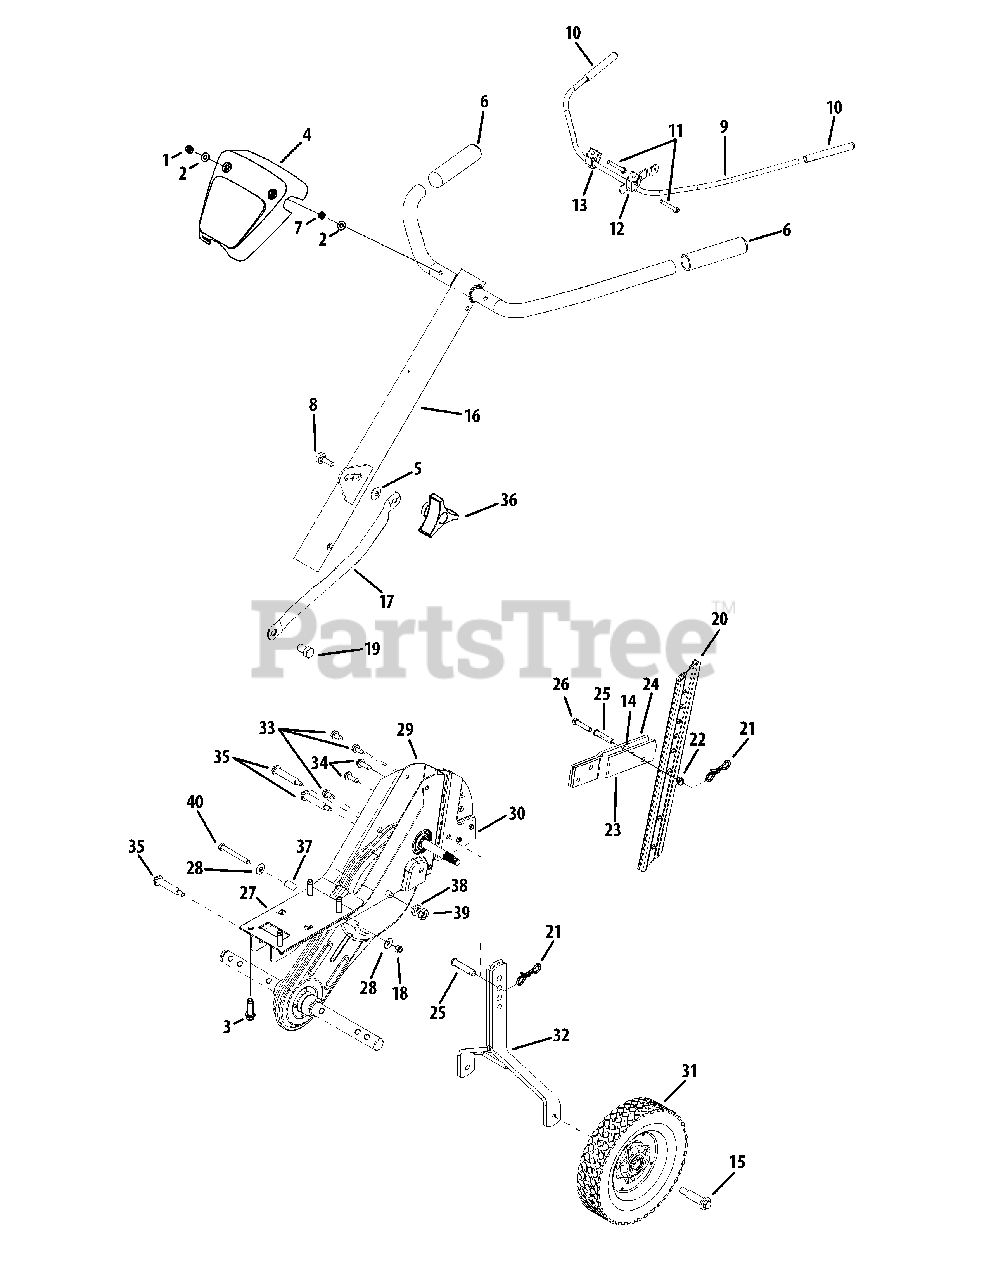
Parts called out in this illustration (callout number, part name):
1	Acorn Lock Nut, 1/4-20
2	Flat Washer, 271" x630"
3	Screw, 3/8-16 x 1250
4	Handle Cover
5	Bell Washer, 34"
6	Handle Grip
7	Jam Nut, 1/4-20
8	Carriage Bolt, 5/16-18 x 1
9	Clutch Handle Assembly
10	Clutch Grip
11	Hex Bolt, 1/4-20 x 225"
12	Clutch Handle Holder
13	Flat Washer, 385" x 62"
15	Shoulder Screw, 496 x 1445
16	Handle Assembly Complete
17	Handle Brace
18	Nylon Hex Nut, 5/16-18
19	Hex Bolt, 1/2-20
21	Cotter Pin, Bow Tie
22	Hex Flange L-Nut, 5/16-18
23	Tail Piece Bracket, Left
24	Tail Piece Bracket, Right
25	Clevis Pin
26	Hex Bolt, 5/16-18 x 15"
28	Bell Washer, 340" x 872"
31	Wheel, 8 x 175
32	Wheel Hanger Bracket Assembly
33	Hex Washer Screw, 5/16-18 x 62"
34	Hex Washer TT-Tap Screw
35	Shoulder Bolt, 5/16-18
36	Hand Knob
38	Lock Washer, 7/16
39	Jam Nut, 7/16-20
40	Hex Bolt, 5/16-18 x 275"
